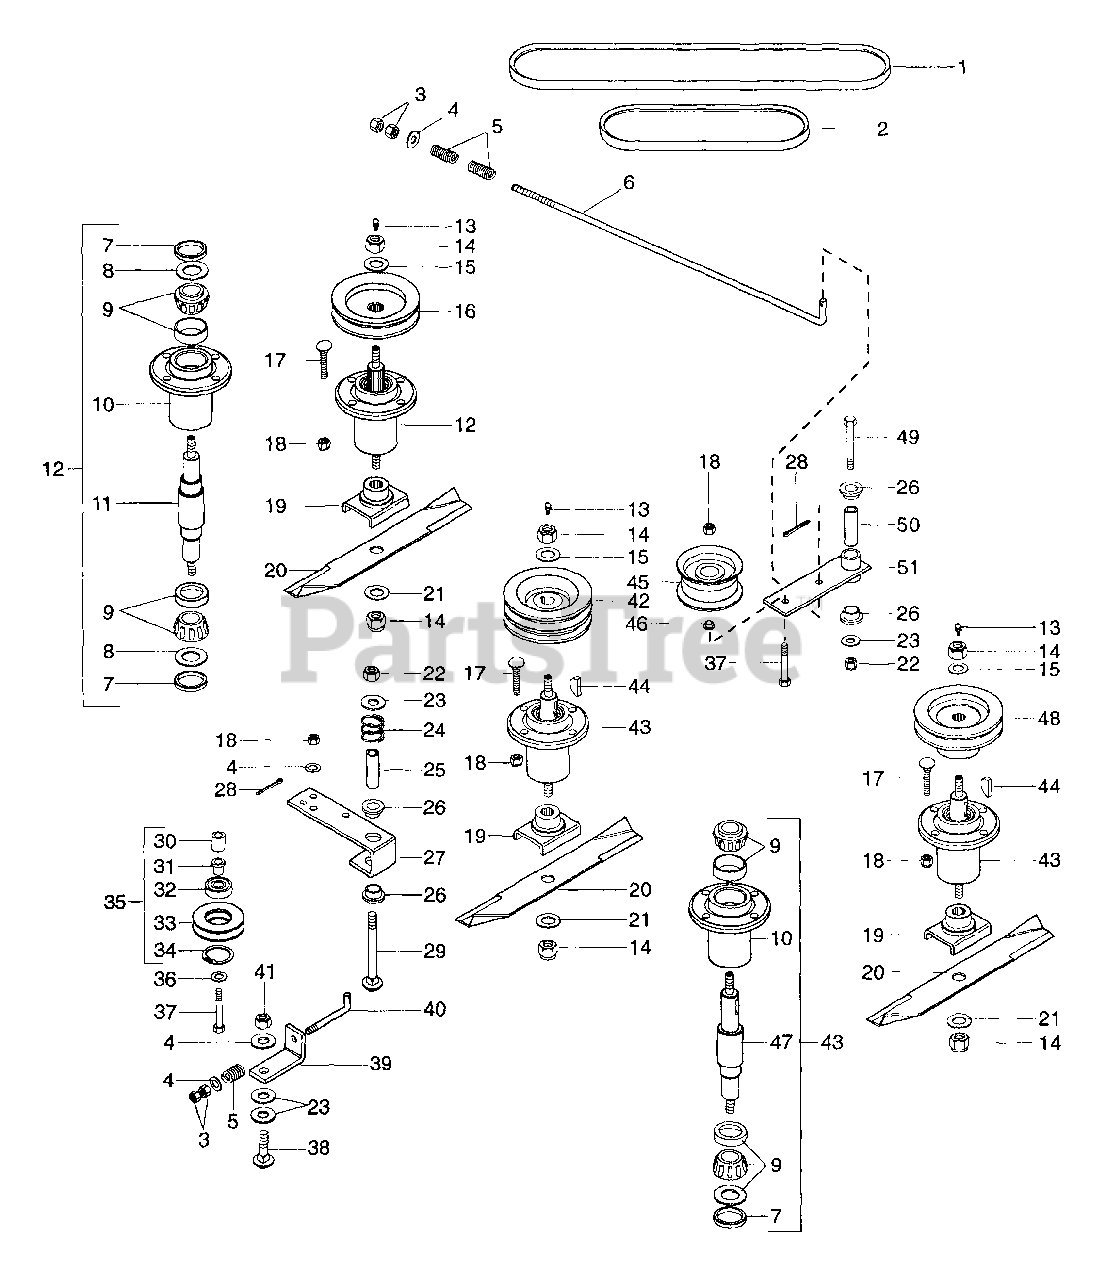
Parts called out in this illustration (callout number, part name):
1	V-Belt A-RMA 47.00 x 17/32
2	V-Belt A-RMA 24.90 x .5001.031
3	Nut-Hex .375-16 Grade 2
4	Washer-Flat-Steel .406 x .812 x .065
5	Spring-Compression .125 x .78 x 1.00
6	Rod, Idler
7	Steel Seal
8	Washer-Flat-Steel .97 x 1.865 x .03
9	Assembly, Bearing Cup & Cone
10	Housing, Bearing
11	Shaft, Spindle
12	Spindle, Assembly
13	Fitting, Lube 1/8
14	Nut-Locking-Nylon .625-11 Grade 2
15	Washer-Flat-Steel .687 x 1.312 x .135
16	Pulley
17	Bolt-Round Head Square Neck .38-16 x 1.375
18	Nut-Locking-Nylon .375-16 Grade 2
19	Weldment, Blade Cradle
20	Blade, 60 Inch Mower
21	Washer-Flat-Steel .656 x 1.312 x .095
22	Nut-Locking .50-13
23	Washer-Flat-Steel .531 x 1.250 x .100
24	Spring-Compression .085 x 1.00
25	Bushing, Steel .560 x .750 x 2.44
26	Bushing-Flange .762 x 1.0 x .580 x 1.48
27	Arm, Idler Pivot
28	Pin-Cotter .09 x 1.0
29	Bolt-Round Head Square Neck .50-16 x 3.50
30	Bushing, Steel .406 x .625 x .480
31	Bushing-Flange .786 x 1.0 x .79
32	Bearing-Ball 1.85 x .787 x .55
33	Sheave, Idler
34	Ring-Retaining-Internal 2.054 x .062
35	Assembly, Idler Sheave
36	Washer-Flat-Steel .375 x 1.125 x .065
37	Bolt-Hex .38-16 x 2.25 Grade 5
38	Bolt-Round Head Square Neck .38-16 x 1.25
39	Bracket, Belt Tensioner
40	Rod, Idler
41	Nut-Locking-Nylon .375-16 Grade 2
42	Sheave, Mower Spindle
43	Assembly, Spindle
44	Key, Woodruff .25 x 1
45	Idler-Flat 4-.687 x .38
46	Bushing-Flange .406 x .88 x .270 x .140
47	Shaft, Spindle
48	Sheave
49	Bolt-Hex .50-13 x 3.00
50	Bushing, Steel .560 x .745 x 2.04
51	Weldment, Idler Arm
